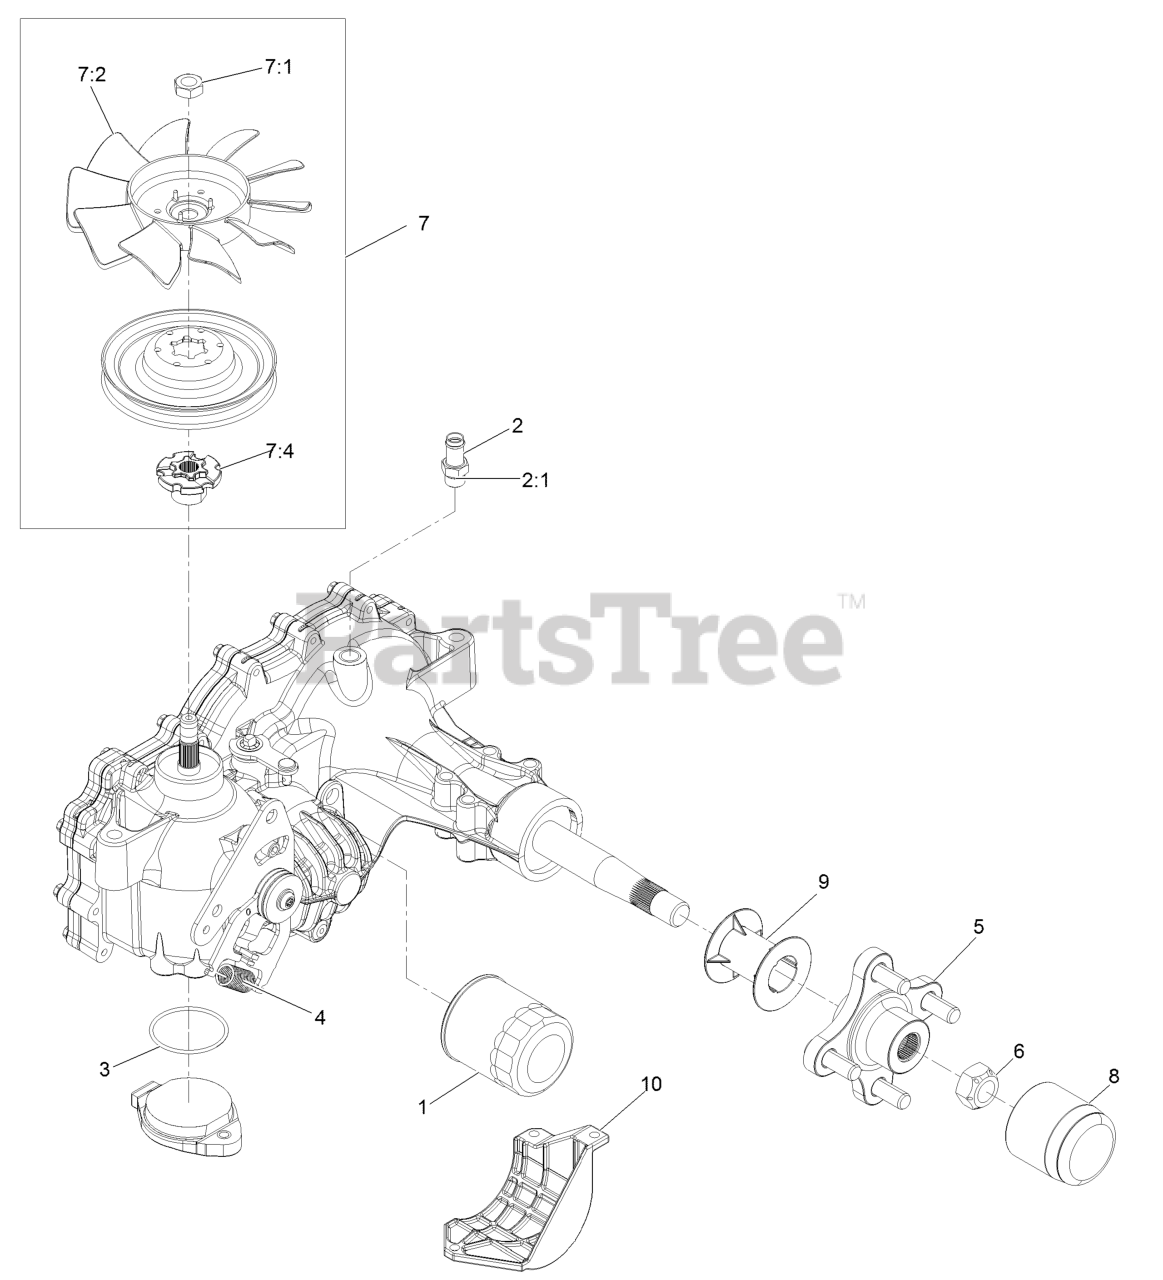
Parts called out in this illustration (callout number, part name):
1	Filter-Hydraulic
2	Adapter-Straight
2:1	O-Ring
3	O-Ring-Charge Seal Cover
5	Hub-Offset
6	Nut-Hub
7	Fan And Pulley Kit
7:4	Hub-Pulley
8	Cap-Axle, Long
9	Tube-Axle
10	Guard-Filter, LH
99	Seal Kit
